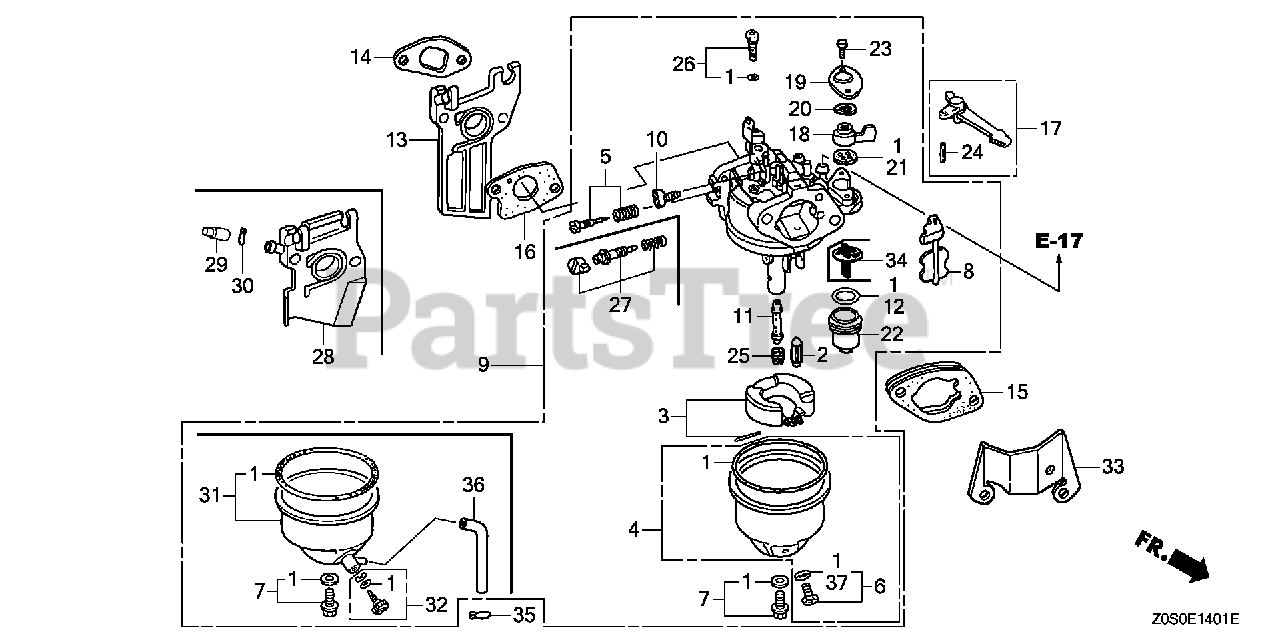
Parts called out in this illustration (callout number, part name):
1	GASKET SET
2	VALVE SET, FLOAT (CARBURETOR NO.) (SEAT NOT INCLUDED)
3	FLOAT SET
4	CHAMBER SET, FLOAT
6	SCREW SET, DRAIN
7	SCREW SET (CARBURETOR NO.)
8	CHOKE SET
9	CARBURETOR ASSY. (BE99T A)
10	SCREW, THROTTLE STOP
11	NOZZLE, MAIN
12	GASKET, FUEL STRAINER CUP
13	INSULATOR, CARBURETOR
14	GASKET, INSULATOR
15	SPACER, CARBURETOR
16	GASKET, CARBURETOR
17	LEVER, CHOKE (STD)
18	LEVER, VALVE
19	PLATE, LEVER SETTING (CARBURETOR NO.)
20	SPRING, PETCOCK LEVER (CARBURETOR NO.)
21	GASKET, VALVE
22	CUP, FUEL STRAINER
23	SCREW, PAN (3X6)
24	PIN, SPRING (2X12)
25	JET, MAIN (#55) (CARBURETOR NO.) Use up to Engine SN BE03A J.
25	JET, MAIN (#58) Use from Engine SN BE30B E.
25	JET, MAIN (#60)
26	JET SET, PILOT (#35)
27	SCREW SET (Honda Code 4219879). (CARBURETOR NO.)
34	FILTER, CUP (CARBURETOR NO.)
37	WASHER, PLAIN (6.2X10.7 DRAIN) (CARBURETOR NO.)
